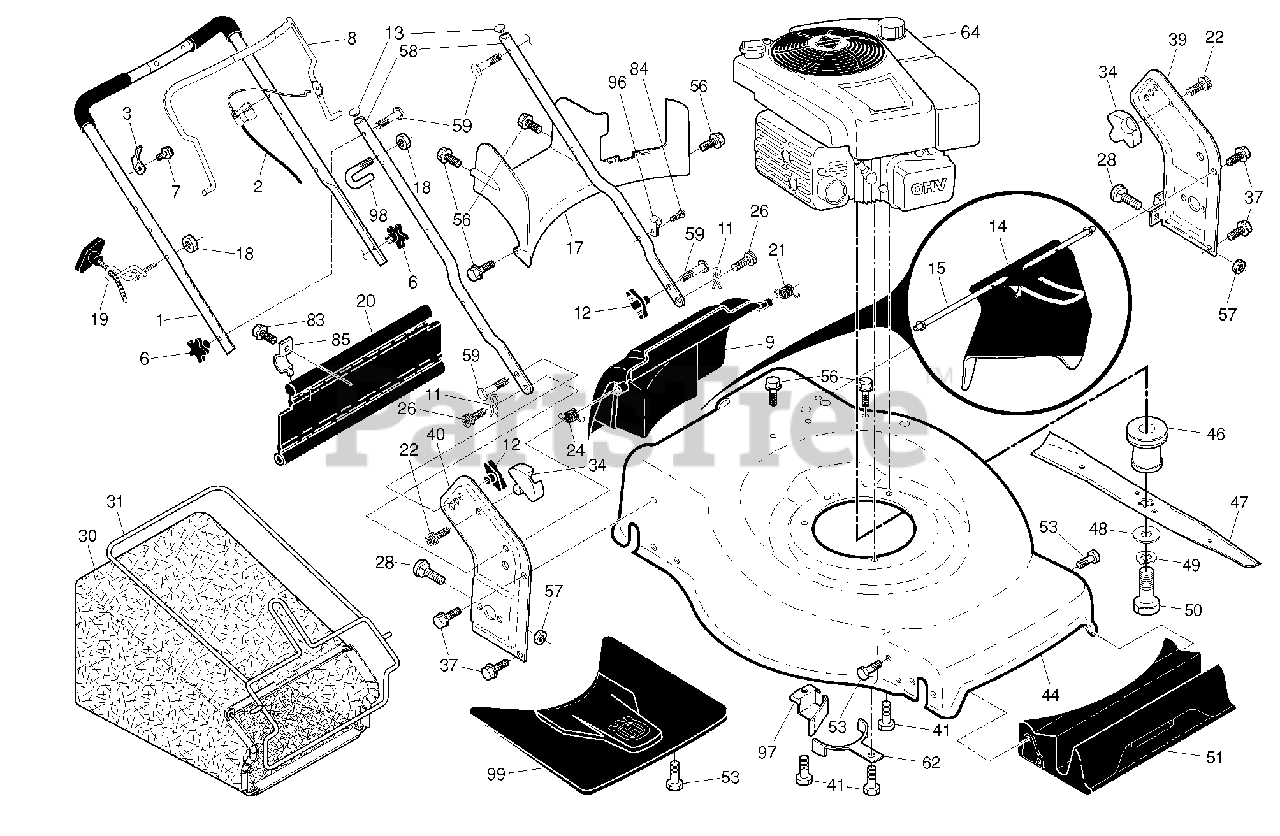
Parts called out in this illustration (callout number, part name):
1	HANDLE.ASM.UPPER.W/GRIP
2	CABLE.MZR.50.SNAP-IN
3	BRACKET.UPSTOP.RT
6	KNOB.HANDLE.PLASTIC.STAR.BLACK
8	BAIL.CONTROL.MZR.BS.ORANGE
9	DOOR.REAR.ASM.22+.HUSQ.FG/RGD
11	COTTER.HAIRPIN.DOOR/HANDLE.PIV
12	KNOB, DEFLECTOR
13	PLUG.PLASTIC.7/8".14-20.GAUGE
14	DEFLECTOR.CHUTE.22+REAR
15	HANDLE DEFLECTOR.22+REAR
17	RP.BAFFLE.REAR.22+.RGD.PL
18	NUT
19	RB GUIDE.ROPE.STD.BLK.ZIN WSL
20	SKIRT.REAR.22+RGD.HIGH WHEEL
21	SPRING.LH.BLACK
22	SCREW.PAN.HEAD.#10
24	SPRING.RH.GRAY
26	SCREW,DOOR/HANDLE.PIVOT
28	BOLT
30	GBAG.A3610247T.SILV.HUSWT.BLUE
31	RB FRAME.GBAG.22PLUS
34	BRACKET.GRASSBAG.ATTACHING.BLK
37	BOLT.5/16HEX.WHS.HD
39	BRACKET.HANDLE.LT.22+.W/DP.GRE
40	RP.BRACKET.ASM.HANDLE.RT.22+.
41	BOLT 3/8-16X1-1/8
44	HOUSING.22+.RWD.HD.WO/PORT.ORN
46	ADPTER.BLAD.25M.VS.22PLU.STAR
47	BLADE.22+.PREMIUM/PREC.FGD/RGD
48	WASHER,HARDEN
49	LOCKWASHER
50	SCREW, HEX HD 3/8-24 X 1-3/8
51	BAFFLE.FRONT.22PLUS.PLASTIC RP
53	SCREW.HI-LO.5/16 X.75
56	SCREW.HX.13X.750
57	NUT.FLANGE.5/16
58	HANDLE.LOWER.22+BT.2PC.GRY
59	BOLT, HANDLE 5/16-18X1.75
62	BRACKET.ENG/BELTKEEPER
83	TAPPING SCREW
84	FASTENER.PUSH.O.250X0.783
85	BRACKET.SKIRT.22+.BZP
96	CLIP.CABLE.BLK
97	BRACKE.BELT.GUIDE.22+
98	CLIP.WIREFORM.PACK.TOR
99	COVER.ASM.FRONT.SHROUD.HUSQ.
